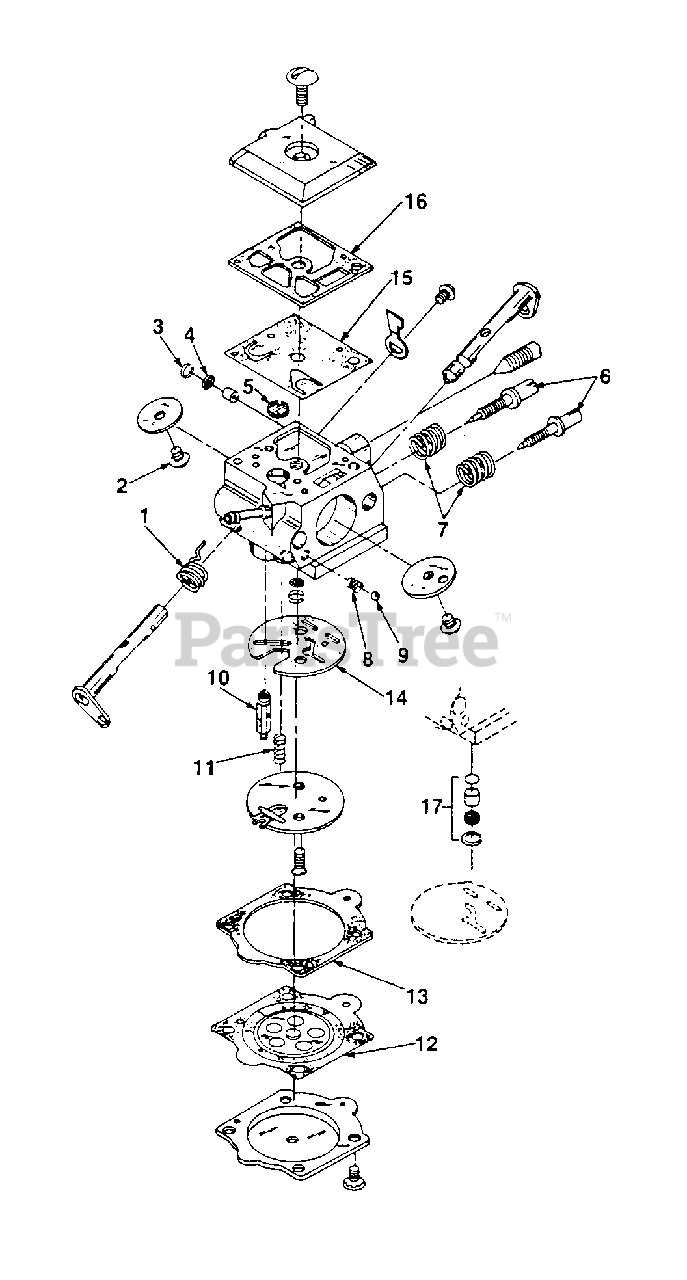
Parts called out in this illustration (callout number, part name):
1	Repair Kit
2	Repair Kit
3	Repair Kit
4	Repair Kit
5	Repair Kit
6	Repair Kit
7	Repair Kit
8	Repair Kit
9	Repair Kit
10	Repair Kit
11	Repair Kit
12	Repair Kit
12	Gasket/Diaphragm Kit
13	Repair Kit
13	Gasket/Diaphragm Kit
14	Repair Kit
14	Gasket/Diaphragm Kit
15	Repair Kit
15	Gasket/Diaphragm Kit
16	Repair Kit
16	Gasket/Diaphragm Kit
17	Check Valve Repair
